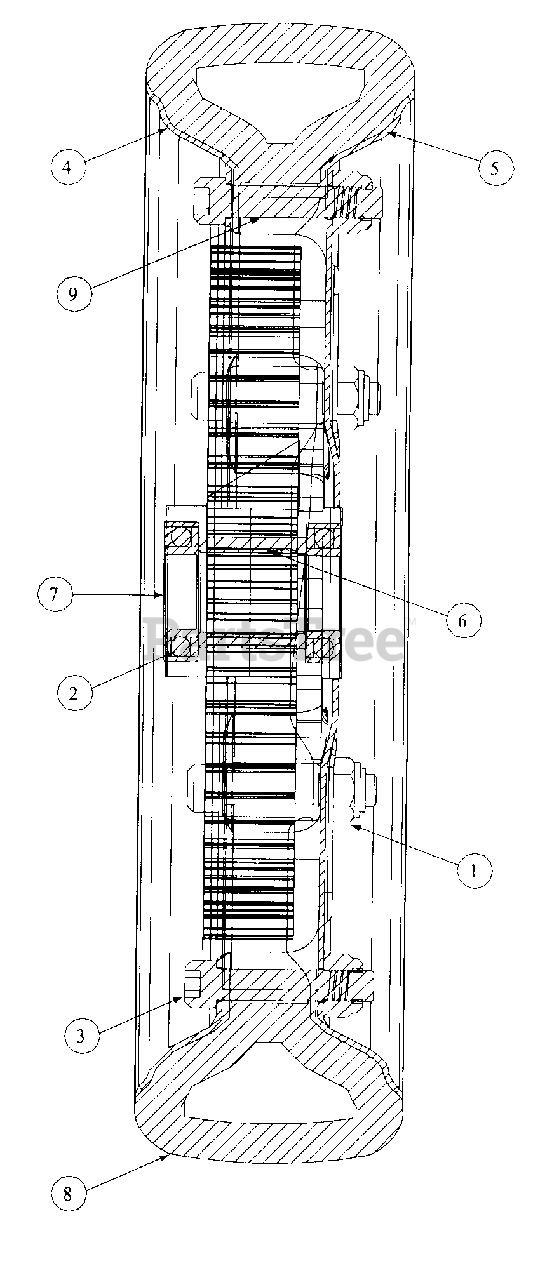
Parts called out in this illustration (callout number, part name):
1	Internal Gear, 63T w/ Hub
2	Socket Screw, 1/4-20 x 1.25
3	Rim Wheel, Inner Half
4	Rim Wheel, Outer Half
5	Spacer, .635 ID x .86 Long
6	Ball Bearing, 15mm x 28mm x 7mm
7	Tire, 9 x 2.125
8	Hex, Lock Nut, 1/4-20
9	Wheel Assembly
